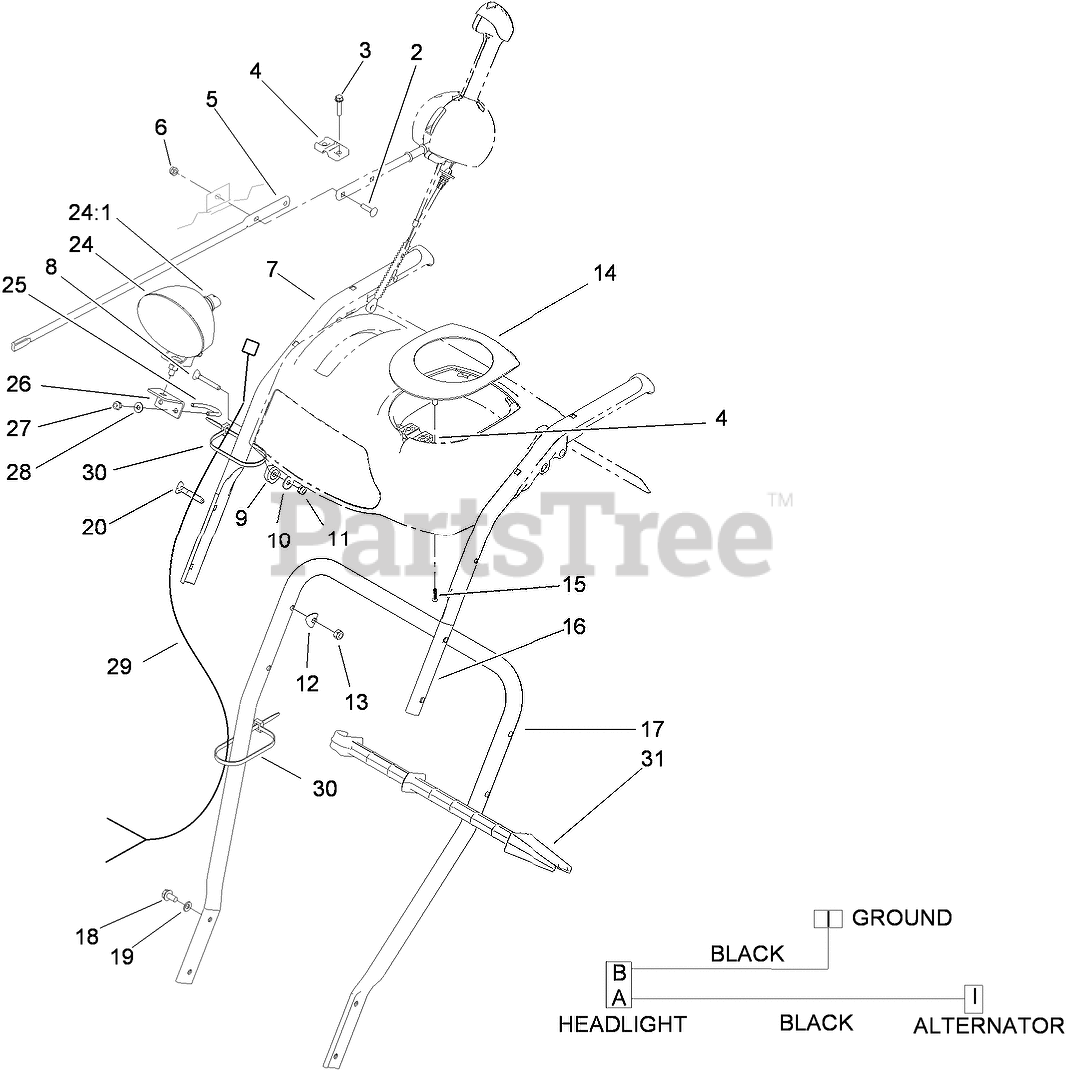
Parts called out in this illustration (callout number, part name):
2	SCREW-CARR
3	SCREW-PLASTITE
4	SUPPORT-ROD
5	ROD-CHUTE, FRONT
6	NUT-LOCK, NI
7	HANDLE-UPPER, RH
8	SCREW
9	CLAMP-CABLE
10	WASHER-PLAIN
11	NUT-LOCK, NI
12	WASHER
13	NUT-LOCK, NI
14	COVER-PANEL, CONTROL
15	SCREW-PPH
16	HANDLE-UPPER, LH
17	HANDLE-LOWER
18	SCREW-HWHTF
19	WASHER-BELLEVILLE
20	SCREW-HANDLE
24	HEADLAMP ASM
24:1	LAMP-12 VOLT
25	CLAMP
26	BRACKET-LIGHT
27	NUT-LOCK, NI
28	WASHER-FLAT
29	HARNESS-WIRE
30	TIE-CABLE
31	STICK-CLEANOUT
